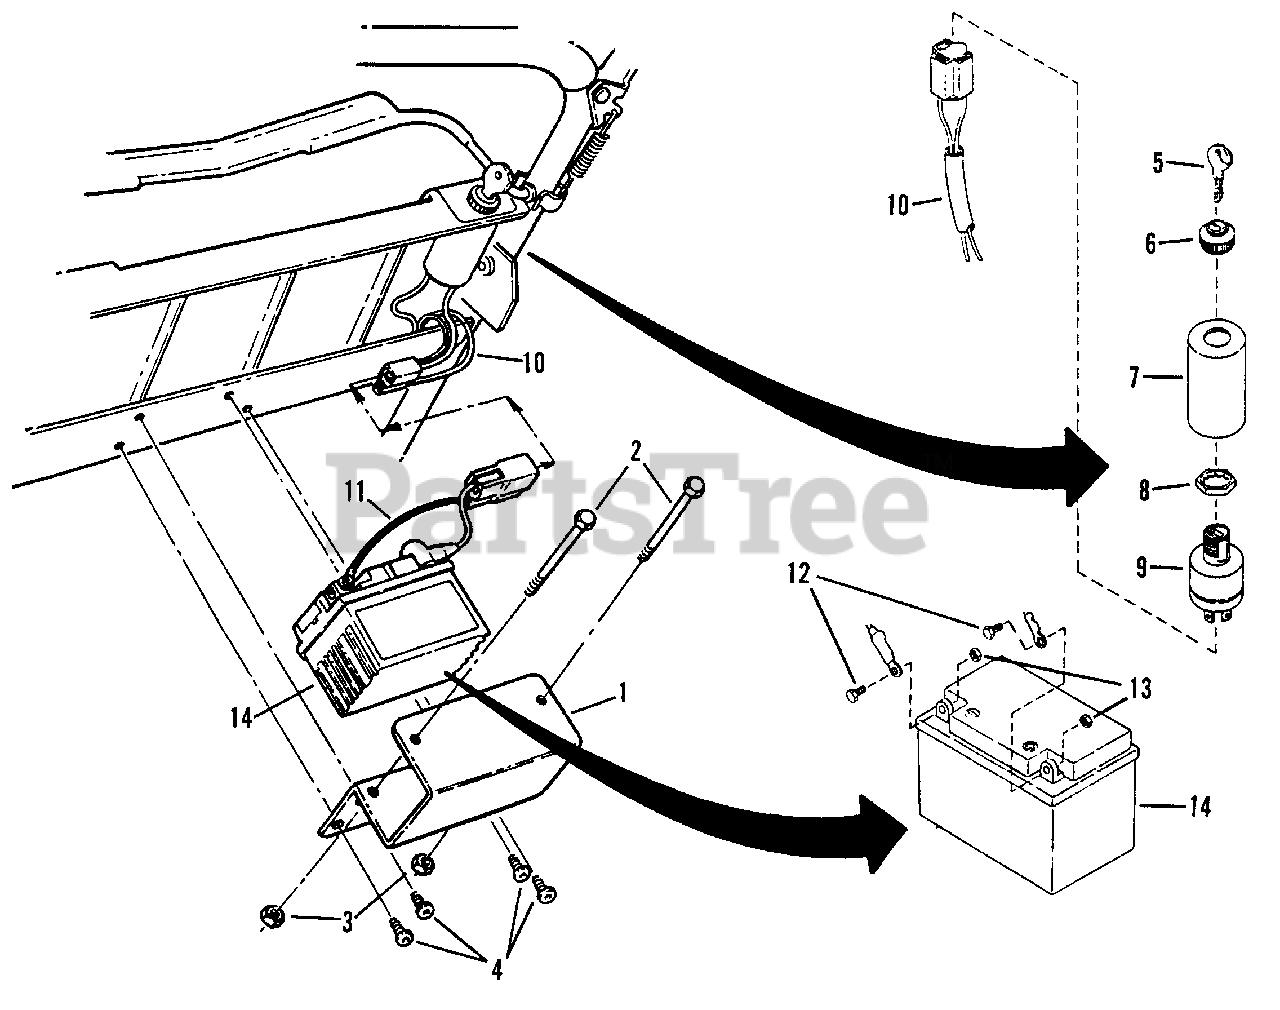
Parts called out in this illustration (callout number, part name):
1	BRACKET, Mounting
2	SCREW, 1/4-20 x 3-1/2" Hex Head Cap
3	NUT, 1/4-20 Hex Center Lock
4	SCREW, 1/4-20 x 5/8" Self-Tapping
5	KEY, Switch
6	ASSEMBLY, Seal & Face Nut
7	COVER, Switch
8	NUT, 3/4-20 Lock
9	SWITCH, Ignition
10	HARNESS, Wiring
11	HARNESS, Battery
12	SCREW, M10-8 x 10mm Hex Head Cap
13	NUT, M10-8 Hex
14	BATTERY 12V
